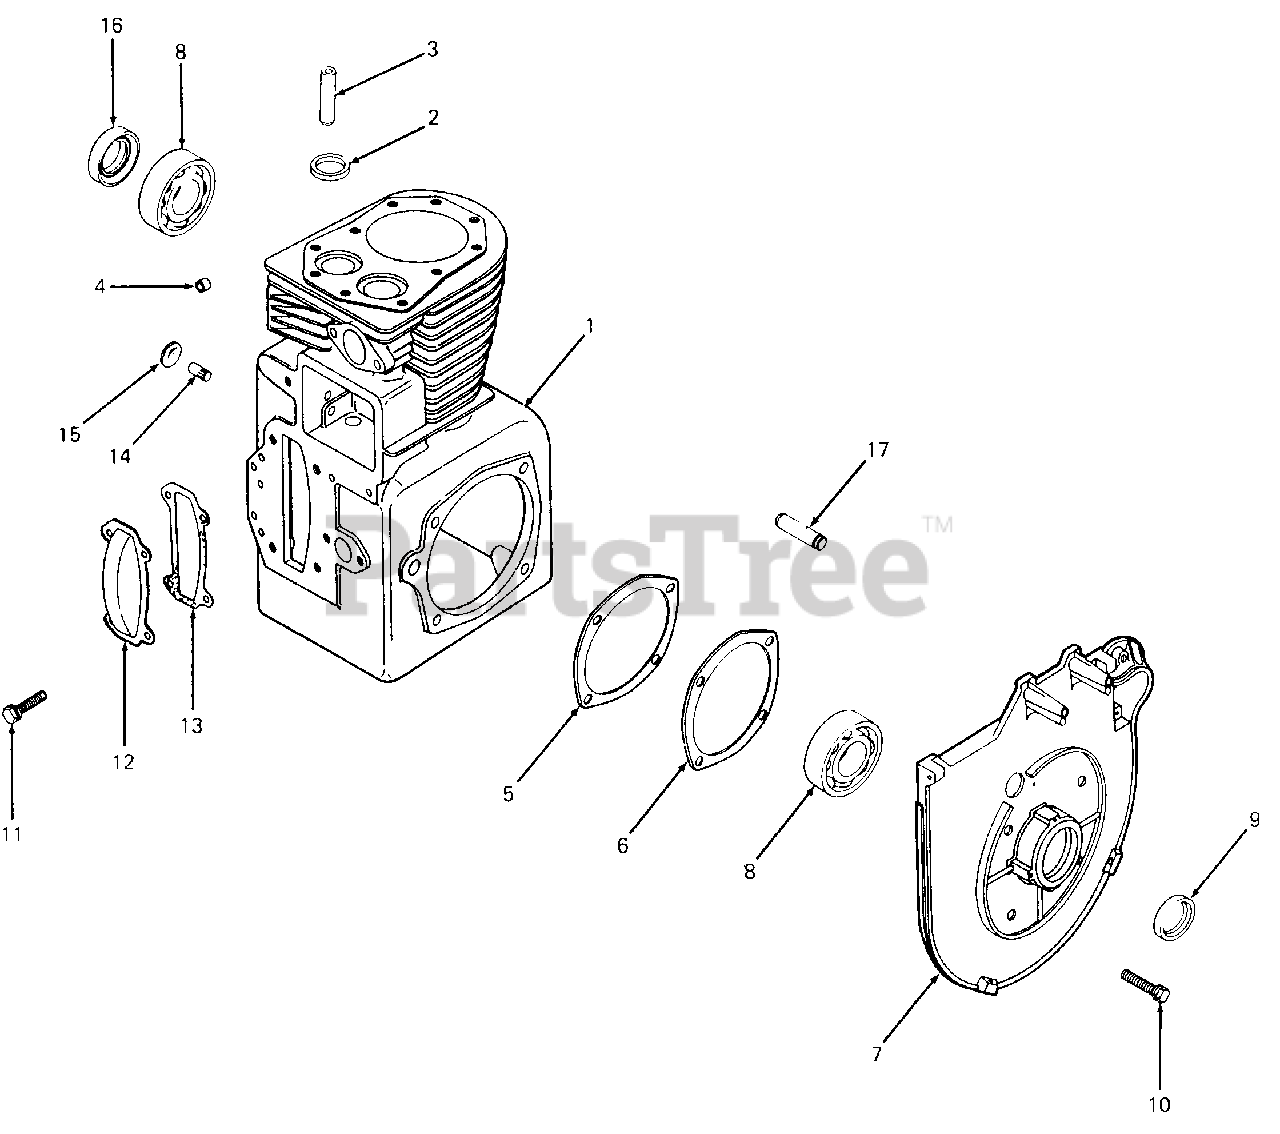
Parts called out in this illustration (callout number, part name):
1	Block, Cylinder Assembly
2	Insert, Exhaust Valve
3	Guide, Valve
4	Bearing, Governor Cross Shaft
5	Gasket, Shim
6	Gasket, Bearing Plate
7	Plate, Bearing
8	Bearing, Ball
9	Seal, Front Oil
10	Screw, HC Sems, 3/8-16 X 1.0 Lg
11	Screw, HC Sems, 1/4-20 X .50 Lg
12	Cover, Camshaft
13	Gasket, Camshaft Cover
14	Shaft, Governor Gear
15	Plug, Expansion
16	Seal, Rear Oil
17	Shaft, Balance Gear
